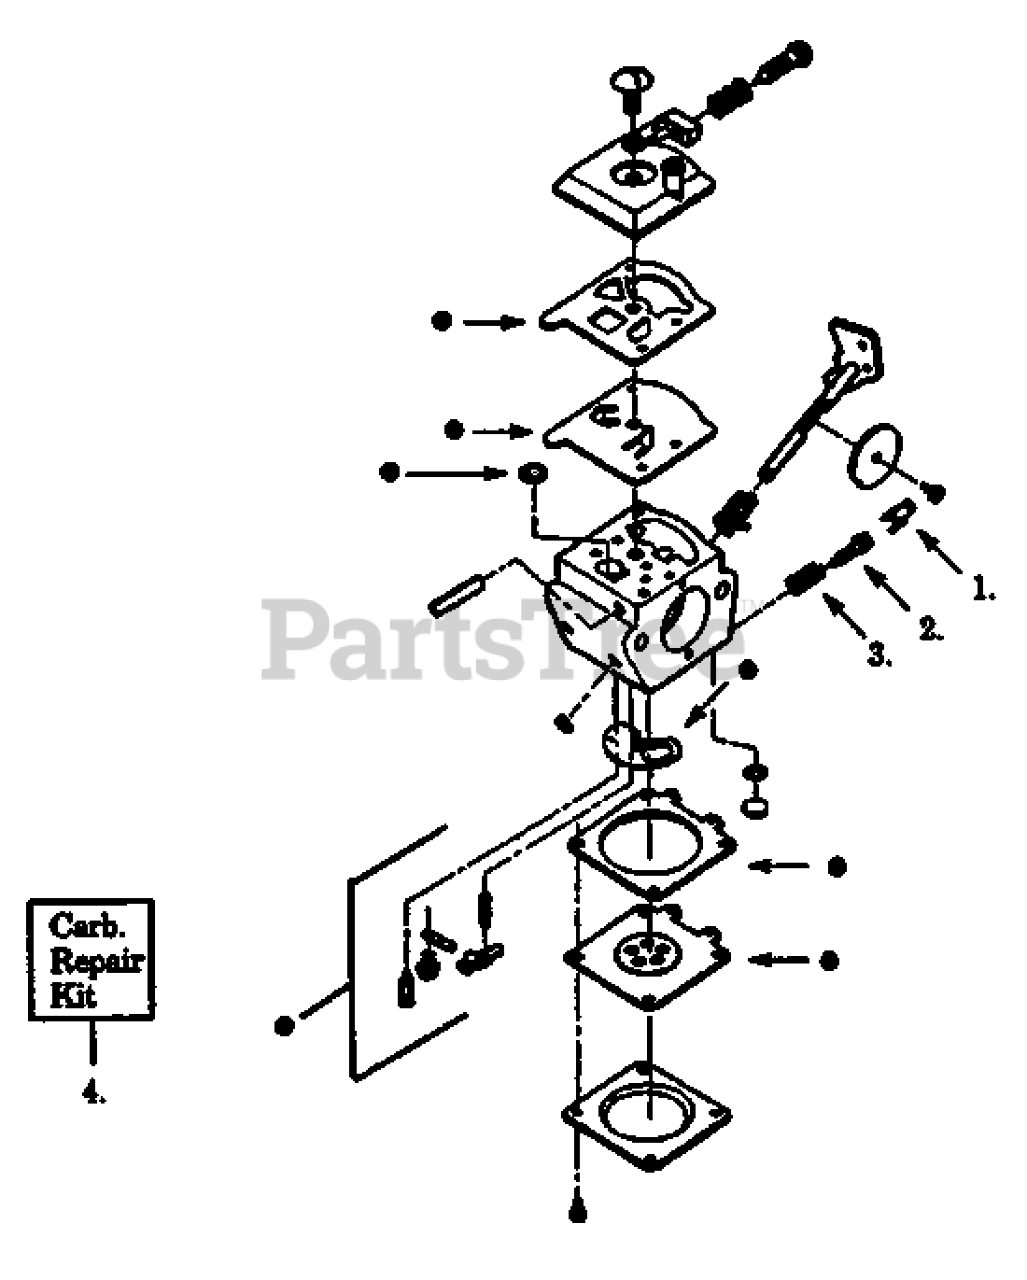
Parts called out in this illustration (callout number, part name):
1	LIMITER CAP NLA
2	Mixture Needle
4	CARBURETOR KIT
